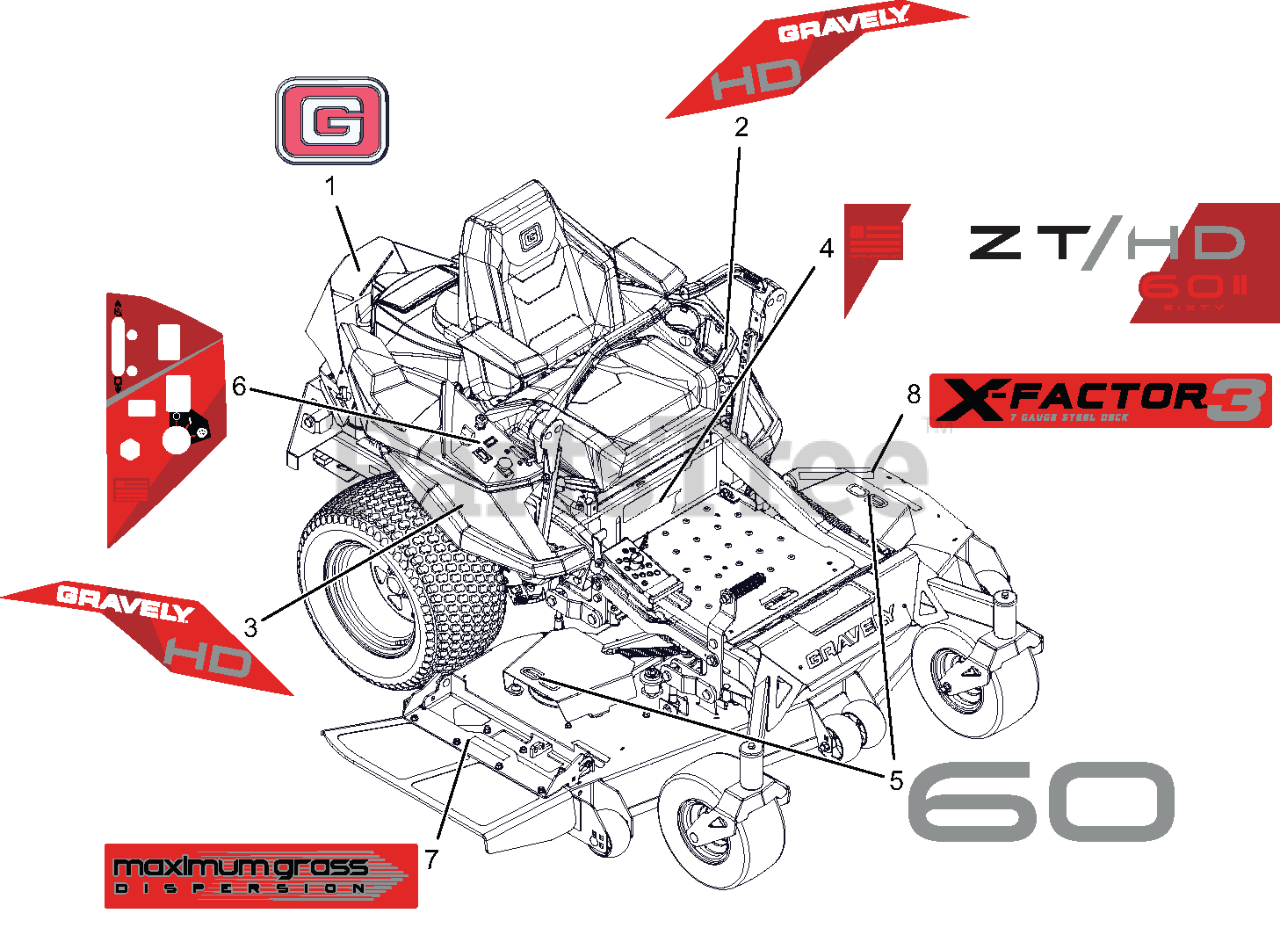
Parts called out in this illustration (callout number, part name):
1	DECAL, GRAVELY BRAND
2	DECAL, FENDER LH - HD
3	DECAL, FENDER RH - HD
4	DECAL, ZT/HD - 60
5	DECAL, DECK - 60
6	DECAL, CONTROL PANEL
7	DECAL, DECK - MAX GRASS
8	DECAL, DECK - X-FACTOR 3 7 GAUGE
